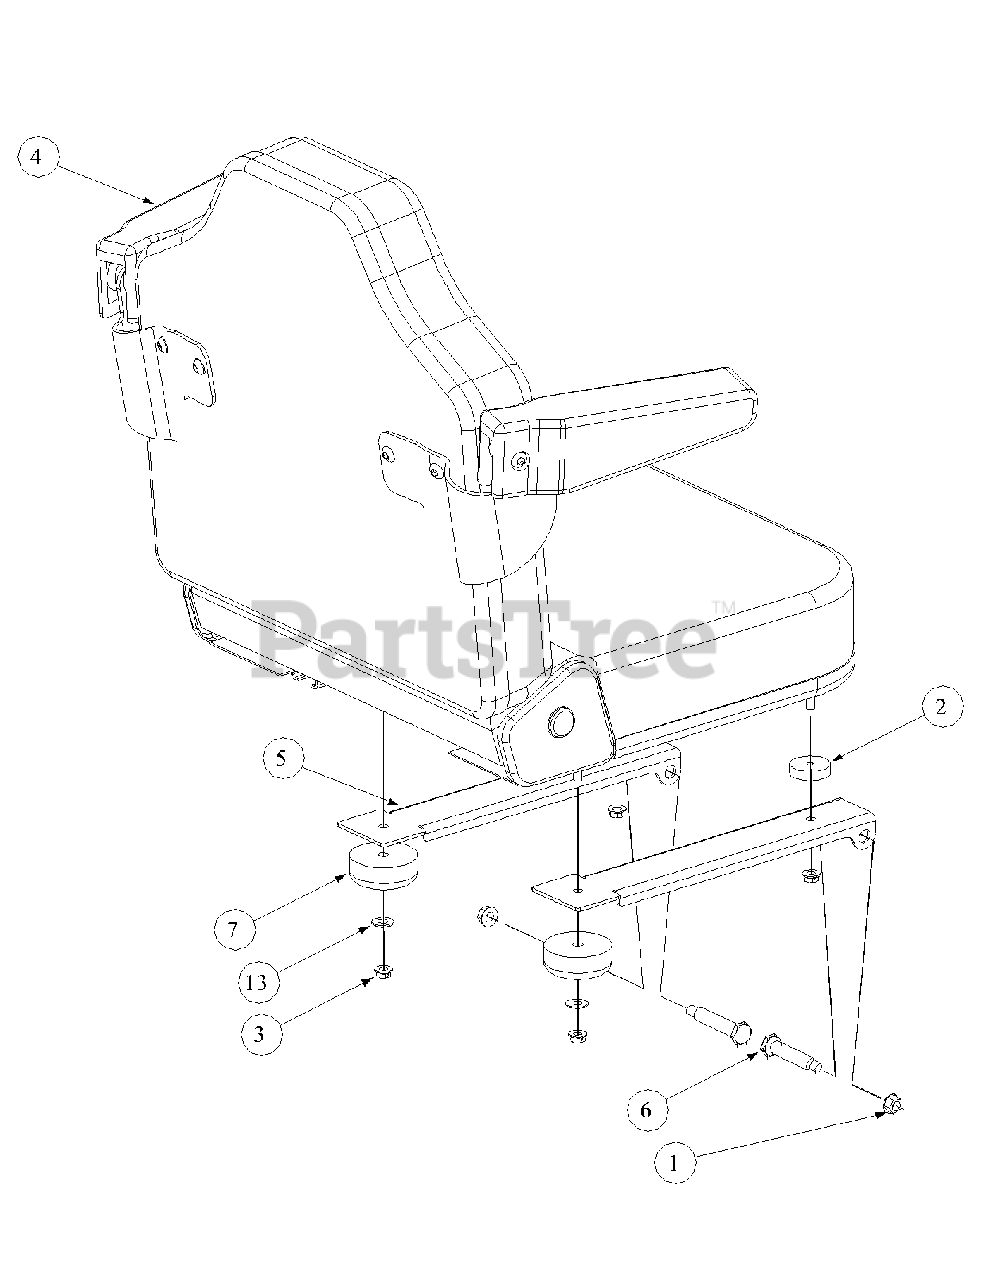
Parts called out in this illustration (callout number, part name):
1	Nut, Hex 3/8-16 Flange Lock
2	Spacer, 0.345 ID x 1.50 OD x .41
3	Lock Nut, Hex Flange, 5/16-18
4	Adjustable Seat, Black embossed,
5	Mounting Bracket, Seat
6	Shoulder Screw, .50x2.345, 3/8-16
7	Grommet, 2.5 OD x 1.0 Long
13	Washer
